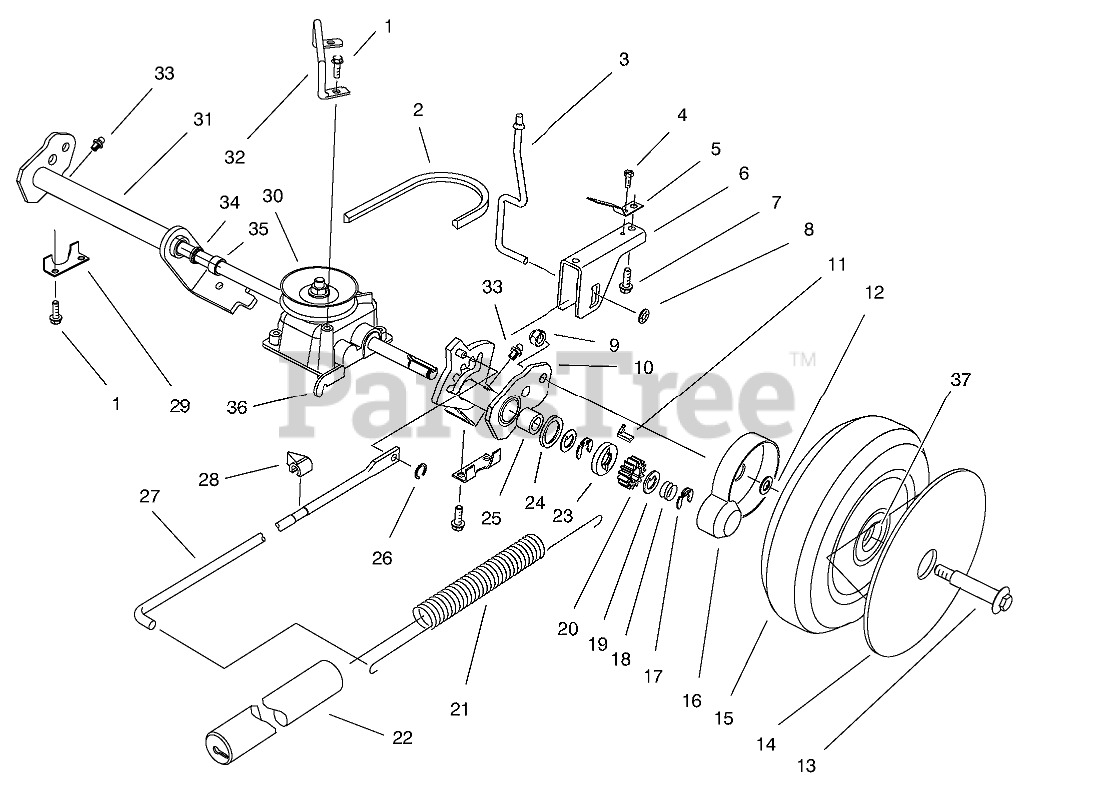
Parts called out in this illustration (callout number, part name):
1	SCREW-HWH
2	V-BELT
3	TRIGGER ROD
4	SCREW 8 - 32 X 250
5	SPRING - TRIGGER RET
6	SADDLE - HOC
7	SCREW
8	PUSHNUT
9	NUT-HEX
10	Arm-Pivot L.H. (Incl. Ref. #25, & 33-35)
11	KEY-ROCKING, LH
12	SPACER-COVER, WHEEL
13	BOLT-WHEEL
14	COVER-WHEEL
15	WHL & TIRE ASSEMBLY
16	COVER-WHEEL
17	RING-CLIP, LOCKING
18	SPRING-COMPRESSION
19	WASHER-THRUST, KEYED
20	GEAR-PINION
21	SPRING-COUNTERBALANCE
22	COVER-SPRING
23	WASHER-CLUTCH
24	RING-FRICTION
25	BEARING-ROLLER
26	GRIP RING
27	LINK ROD
28	INDICATOR-HEIGHT OF CUT
29	REAR SECURING PLATE
30	GEAR CASE ASSY
31	Arm-Pivot R.H. (Incl. Ref. #25, & 33-35)
32	Retainer Belt
33	FITTING-GREASE
34	SEAL-OIL
35	BUSHING
36	Bracket-Traction
37	BUSHING
